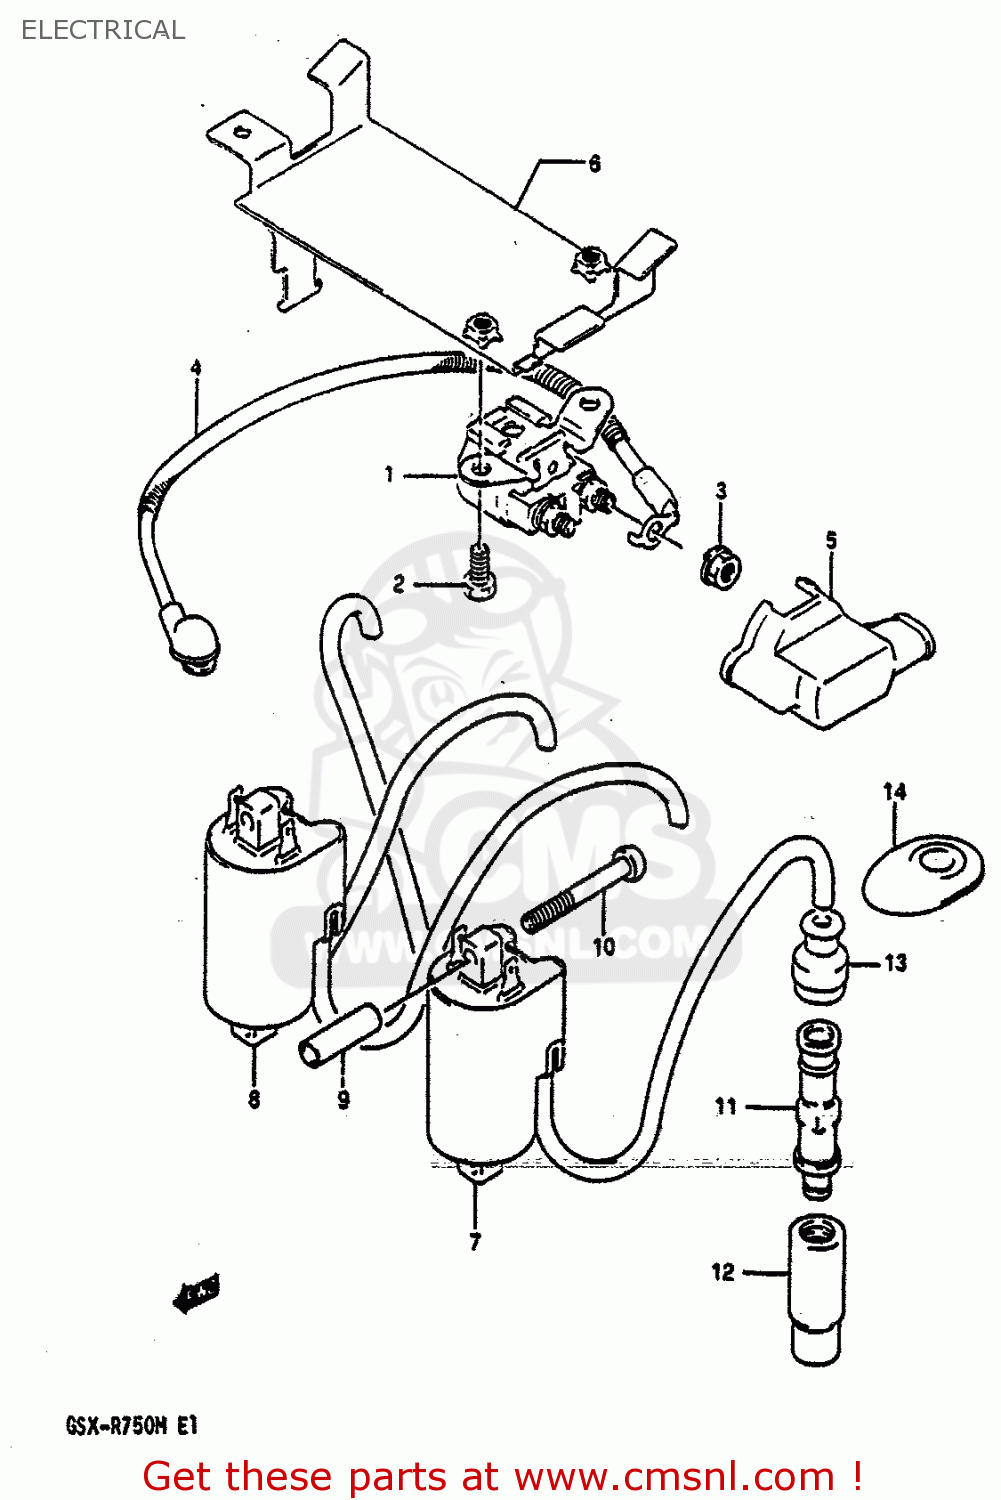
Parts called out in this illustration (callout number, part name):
1	RELAY ASSY,STARTING MOTOR
2	SCREW(6X8)
3	NUT
4	WIRE,STARTER MOTOR
5	CAP,STARTER RELAY
6	HOLDER COMP,ELECTRONIC PARTS
7	COIL ASSEMBLY,IGNITION (1-4)
8	COIL ASSEMBLY,IGNITION
9	SPACER (6.5X10.5X31.7)
10	SCREW
11	CAP,SPARK PLUG
12	SEAL,SPARK PLUG
13	SEAL,HIGH TENSION CORD
14	COVER,SPARK PLUG CAP
